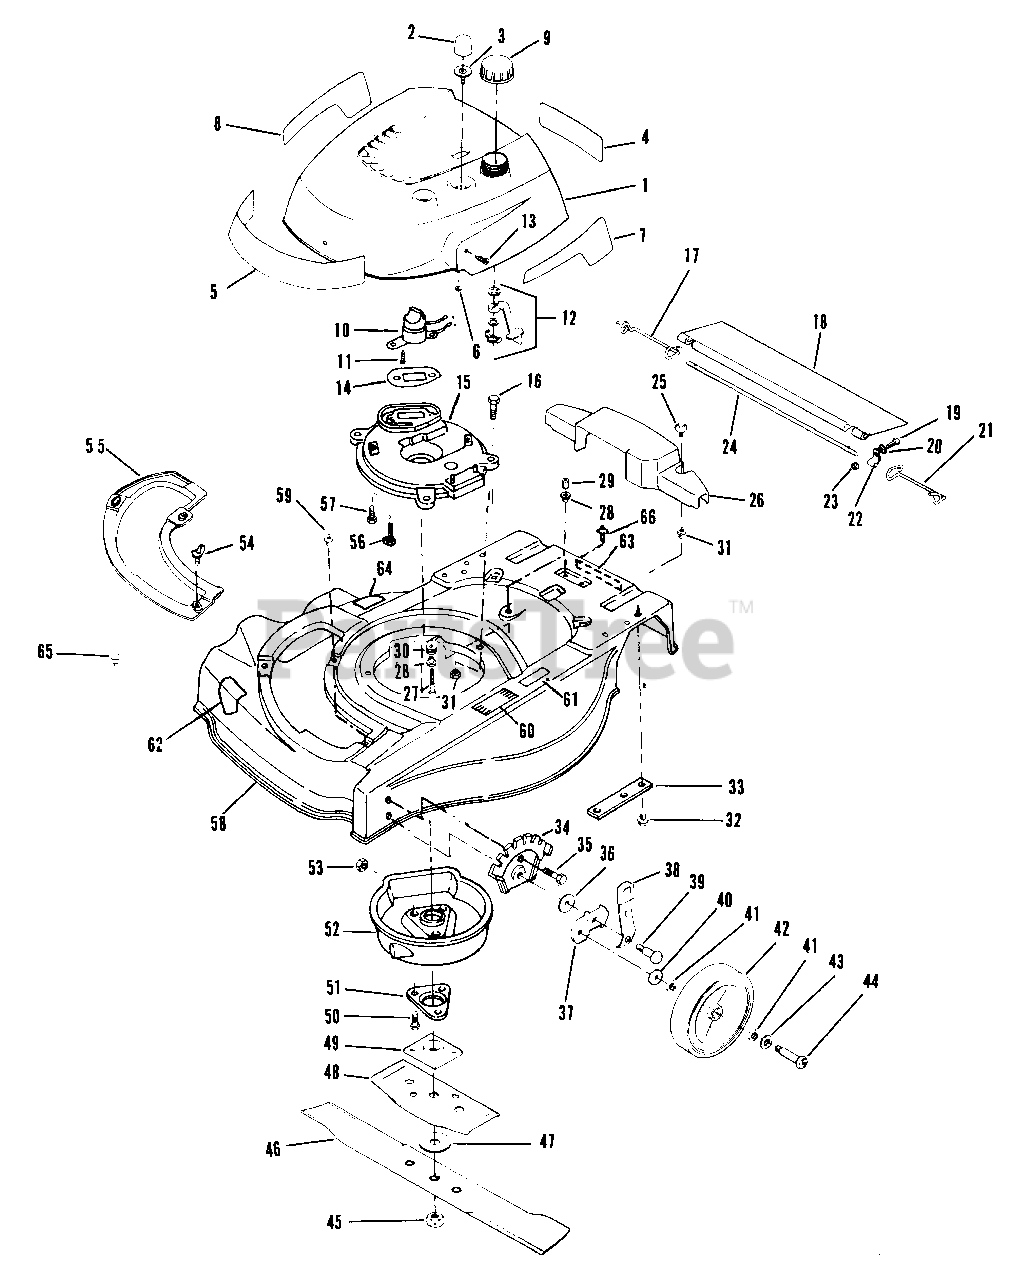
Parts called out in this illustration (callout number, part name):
1	Shroud-Engine
2	Bulb-Primer
3	Base-Primer
4	Decal-Instructions
5	Decal-Lawn-Boy
6	Nut-Primer Base
7	Decal-L.H. 21"
8	Decal-R.H. 21"
9	Fuel Cap
10	Switch-On-Off
11	Screw
12	Fuel Shut-Off Assembly
13	Screw-Shroud Mounting
14	Gasket-Exhaust
15	Plate-Muffler
16	Screw-Muffler Plate to Housing
17	Spring-R.H.
18	Shield-Trailing
19	Screw
20	Washer
21	Spring-L.H.
22	Clamp
23	Nut
24	Rod-Trailing Shield
25	Screw-Axle Cover Mounting
26	Cover-Drive Axle
27	Screw-Transmission to Housing
28	Spacer
29	Spacer
30	Grommet
31	Nut-Muffler Plate to Housing
32	Screw-Handle Bracket to Housing
33	Plate-Handle Bracket Support
34	Plate-Height Adjust Backup
35	Screw-Height Adjust Plate
36	Washer
37	Bracket-Wheel Height Adjustment
38	Knob & Spring Assembly
39	Shoulder Bolt
40	Washer
41	Washer-Felt
42	Wheel-Front
43	Washer
44	Bolt-Wheel-Front
45	Nut-Blade
46	Blade-21"
47	Washer-Blade
48	Stiffener-Blade
49	Collar & Plate Assembly
50	Screw
51	Support-Crankshaft
52	Muffler Cover Assembly
53	Nut
54	Wing Screw
55	Cover Plate
56	Screw-Muffler Plate to Block
57	Screw-Muffler Plate to Block
58	Housing
59	Grommet
60	Pad-Starting
61	Decal-Starting Pad
62	Decal-Blade Contact Warning
63	Decal-Caution
64	Decal-Discharge Area
65	Screw-Sems-Plate & Chute Mounting
66	Rivet-Serial Plate
